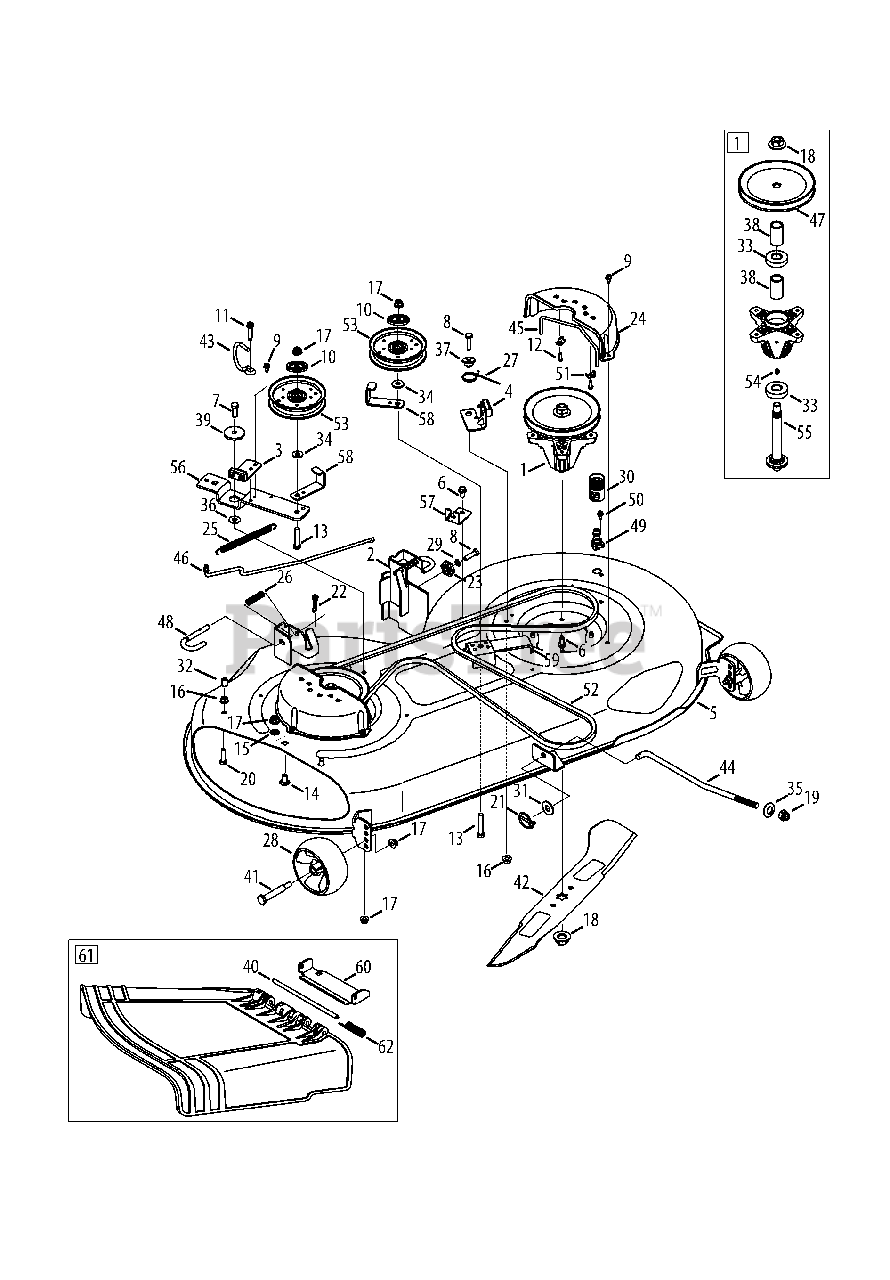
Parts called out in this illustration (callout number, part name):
1	Spindle Ass’y, Pulley, 6.93 Dia
2	Bracket Ass’y, Deck, Hanger LH
3	Brake Ass’y, Deck
4	Brake Ass’y, Deck
5	Deck Ass’y, Offset, 46" 2W
6	Screw, Self-tapping, 5/16-18, .750,
7	Hex Screw, 3/8-16, 1.00
8	Hex Screw, 5/16-18, 1.25
9	Screw, Self-tapping, 1/4-20, 0.500,
10	Pulley Cap
11	Screw, Self-tapping, 1/4-20, .75,
12	Screw, #10-16:.625
13	Hex Screw, 3/8-16, 2.00
14	Bolt, Carriage, 3/8-16, 0.75
15	Nut, Push, 3/8
16	Nut, Flange Lock, 5/16-18
17	Nut, Flange Lock, 3/8-16
18	Nut, Flange, 5/8-18
19	Nut, Lock, 1/2-13
20	Hex Cap Screw, 5/16-18 x 1.00
21	Pin, Lynch, .1875
22	Bow-Tie Cotter Pin, 72
23	Gear, Deck, Adjustment
24	Belt Cover
25	Spring, Extension, .62 Dia x 6.12
26	Spring, Comp, .535 OD x 1.751
27	Spring, Torsion, .992 I.D x 1.17 O.D
28	Wheel, Deck, 5.0 Dia Ball
29	Washer, Lock, 5/16, Regular Duty
30	Water Nozzle Adaptor
31	Washer, Flat, .531 x 1.25 x .100
32	Cap, .290 x .500
33	Ball Bearing, .787 ID x 1.85 OD x .551
34	Washer, Flat, .385 x .870 x .092
35	Washer, Bell, .63 x 1.25 x .18
36	Washer, Flat, .385 x 1.0 x .030
37	Spacer, Shoulder, .50 x .145
38	Spacer, .792 x 1.060 x 1.860
39	Spacer, Shoulder, .8840 x .190
40	Hinge Pin
41	Bolt, Shoulder, .496 x 2.50, 3/8-16
42	Blade
43	Rod, Keeper, Belt
44	Rod, Lift, Deck, Frt, 13.7
45	Rod, Keeper, Belt
46	Rod, Control, Brake
47	Pulley, Deck, 6.93 Dia
48	Rod, Handle, Deck Release
49	Deck Wash Nozzle
50	Shoulder Screw, 1/4-20 x 0.50
51	Clamp, Casing
52	Belt, V-Type
53	Pulley, Idler, 4.25"Dia
54	Fitting, 3/16, Lnc#70, Drive Lube
55	Shift, Spindle, 6.11.
56	Bracket, Idler, Pivot
57	Bracket, Cable, Deck Engage
58	Bracket, Guard, Belt, 4.25 Pulley
59	Bracket, Support, Deck Stationary Idler
60	Bracket, Chute
61	Chute Ass’y, Deflector
62	Torsion Spring, .44 ID x 2.0
